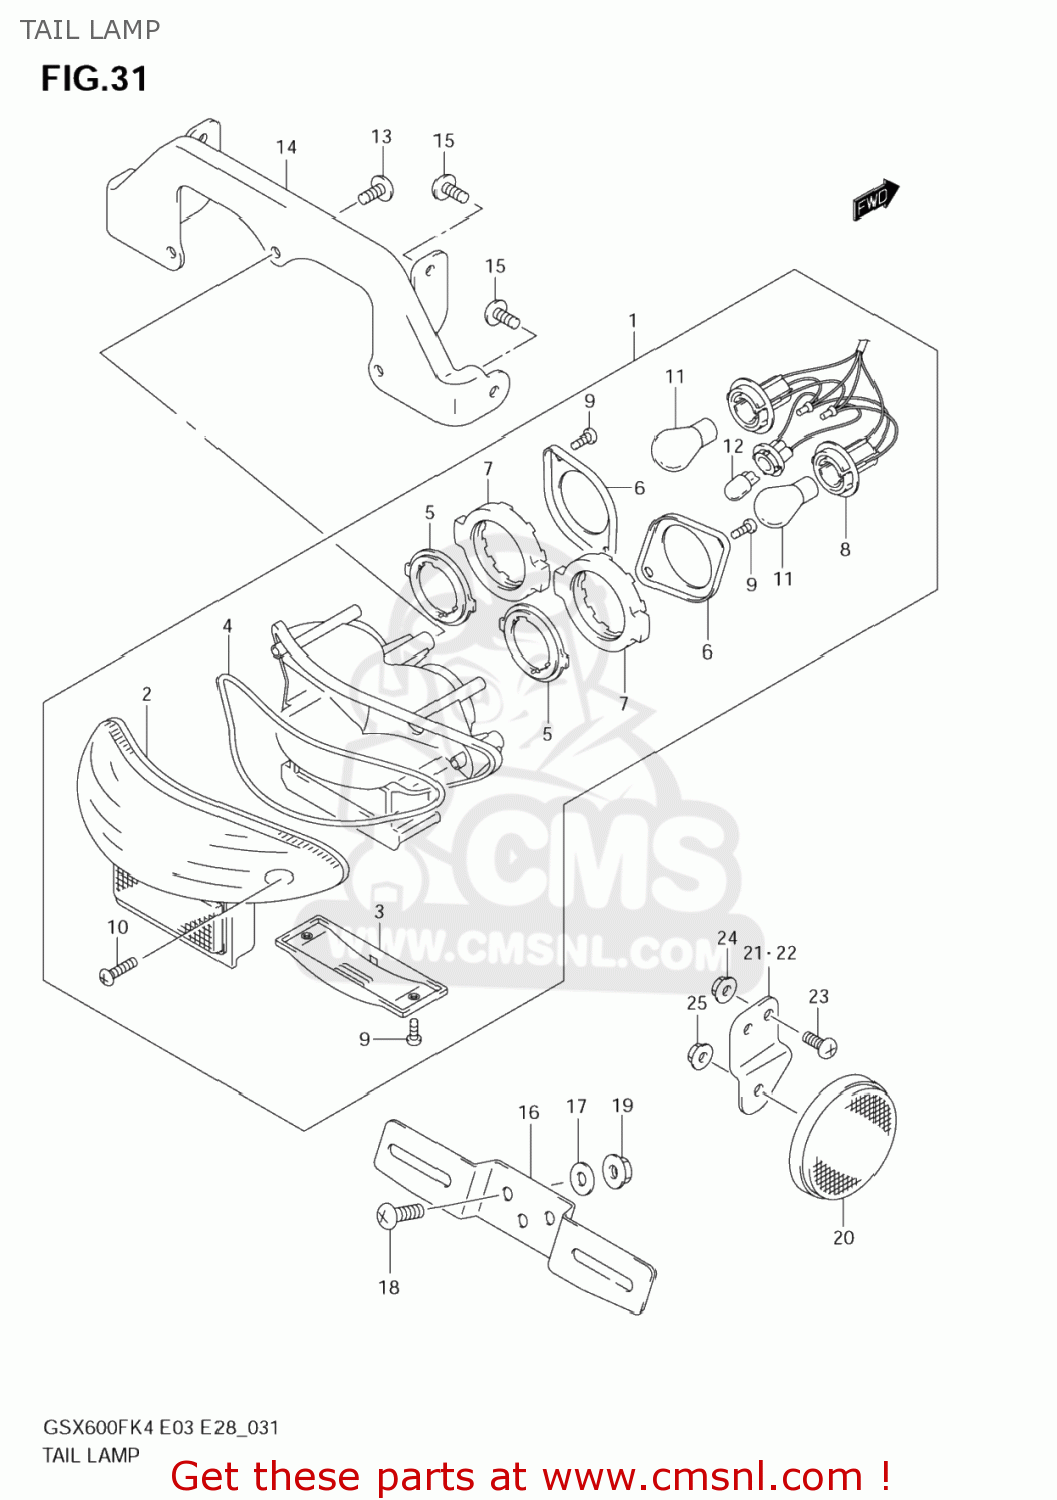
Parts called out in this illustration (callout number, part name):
1	LAMP ASSY,RR COMBINATION
2	LENS
3	LENS,LICENSE LAMP
4	GASKET (NAS)
5	PLATE NO.1
6	PLATE NO.2
7	CUSHION
8	SOCKET & CORD
9	SCREW
10	SCREW
11	BULB(12V21/5W)
12	BULB(12V5W)
13	SCREW
14	BRACKET,RR COMBINATION LAMP
15	SCREW
16	BRACKET,LICENSE PLATE
17	WASHER(6.5X20X1.6)
18	SCREW
19	NUT
20	REFLECTOR ASSY,RR SIDE
21	BRACKET,RR SIDE RR,R
22	BRACKET,RR SIDE RR,L
23	SCREW
24	NUT
25	NUT
